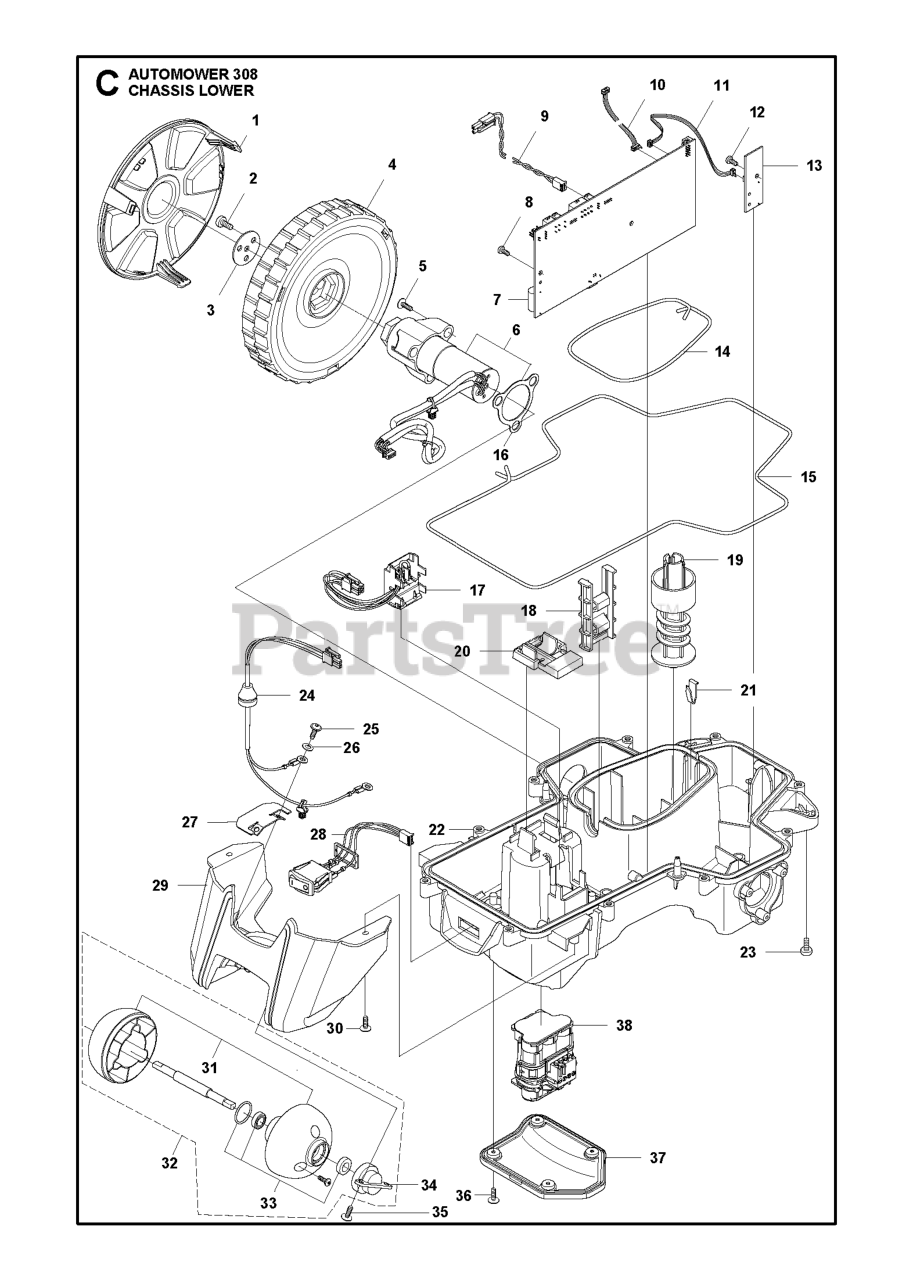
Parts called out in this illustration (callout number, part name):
2	SCREW ITXPANM M5X12 8.8 ZP-BC
3	WASHER DRIVE WHEEL
4	WHEEL DRIVE WHEEL
5	SCREW 14MM
6	WHEEL MOTOR ASSY WHEEL MOTOR K
8	SCREW
9	LOOM BUZZER EXTENSION
12	SCREW
14	SEALING STRIP P1
15	SEALING STRIP P1 CHASSIS
16	GASKET MOTOR FLANGE
17	LOOM BATTERY 18 V LLITHIUM
18	GUIDE RAIL MOTOR BOWL
19	SCREW HEIGHT ADJUSTMENT
20	LOCK BATTERY PLUG
21	LOCKING SPRING
23	SCREW ITXPANM M5X12 8.8 ZP-BC
25	SCREW 14MM
26	FIBER WASHER
28	LOOM ON/ OFF
29	HOUSING REAR WHEEL FLAME RETAR
30	SCREW 14MM
31	REAR WHEEL REAR WHEEL KIT, LEF
32	REAR WHEEL REAR WHEEL KIT COMP
33	REAR WHEEL BEARING AND SEALING
34	BEARING HOUSING REAR WHEEL
35	SCREW 14MM
36	SCREW ITXPANT
37	COVER BATTERY
38	BATTERY LI-ION
